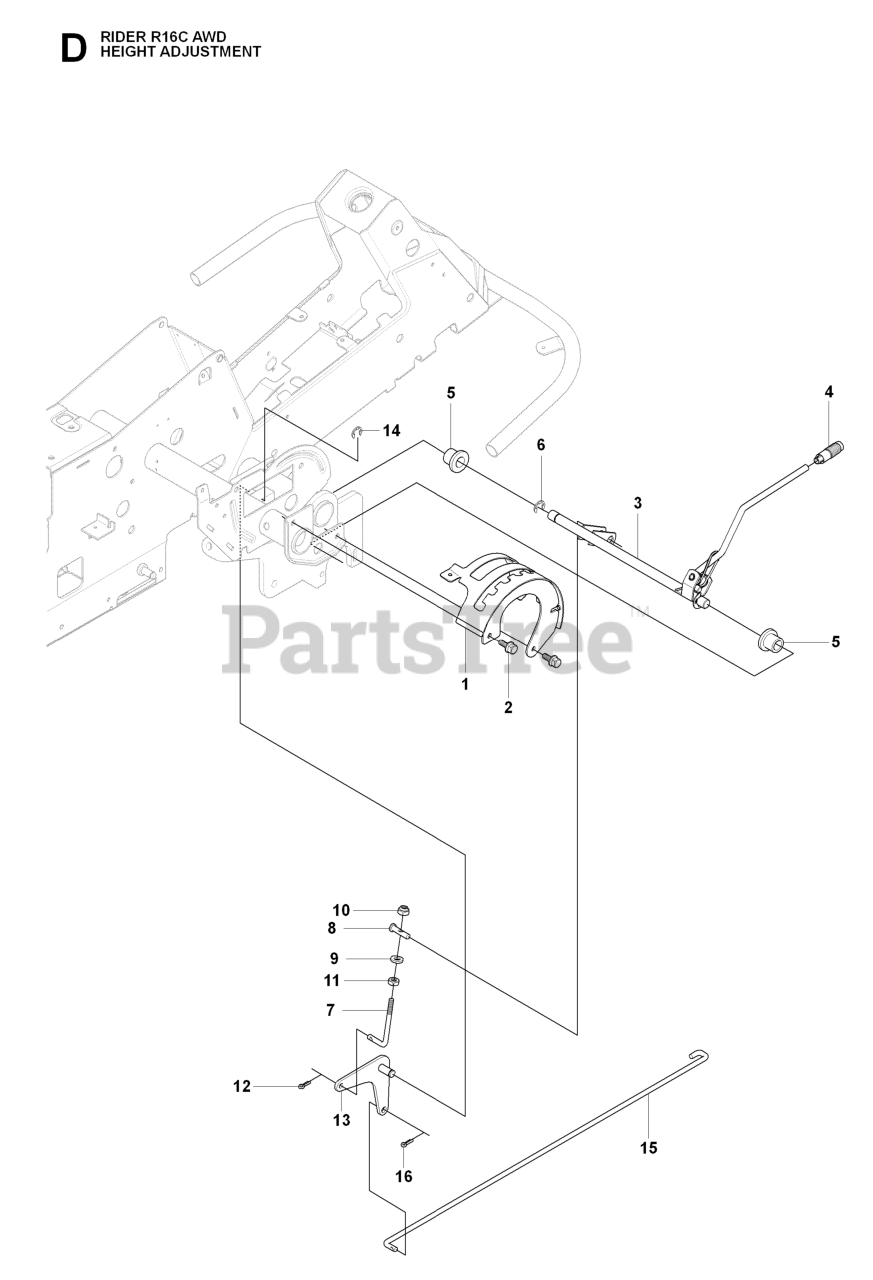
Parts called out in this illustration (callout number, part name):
1	CONTROL PLATE
3	HEIGHT ADJUSTER
4	GEAR STICK KNOB
5	BUSHING
9	WASHER
10	LOCKNUT M8
11	NUT
13	LINK HEIGHT ADJUSTMENT
14	RETAINING RING
15	CONNECTION ROD
